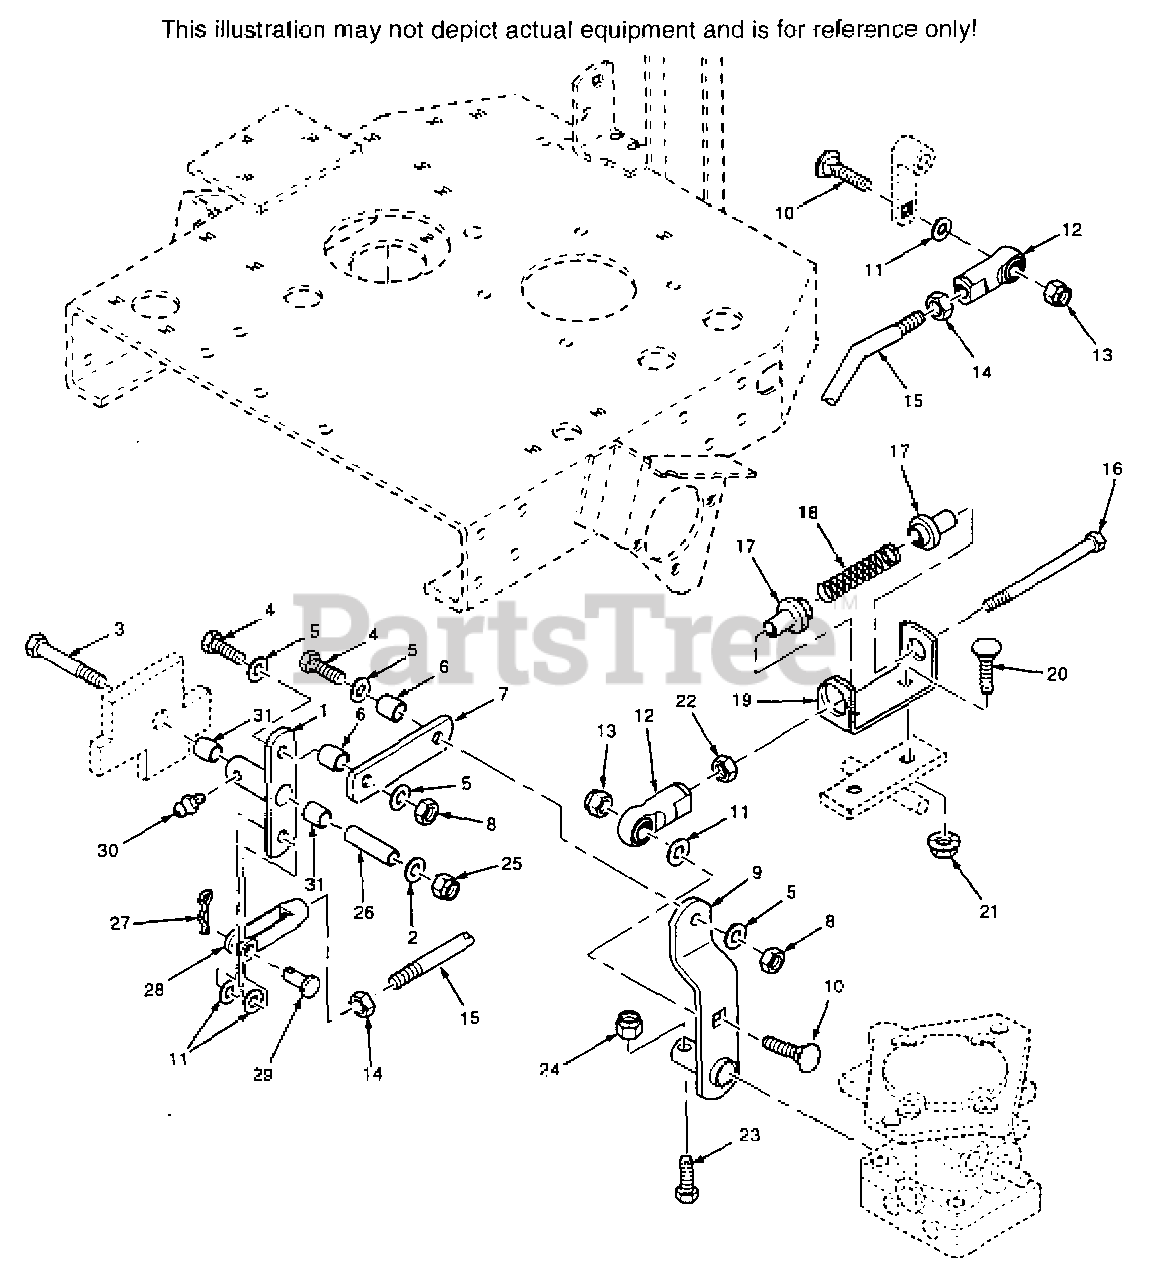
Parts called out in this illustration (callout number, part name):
1	CONTROL LINKAGE, BELLCRANK
6	SLEEVE, PUMP CONTROL LINK
7	LINK, SPEED CONTROL
9	CONTROL ARM, PUMP
11	FLATWASHER, 3/8 X 15/16 X 12 GA.
12	ROD END, RH FEMALE THD 3/8-24
15	CONTROL ROD
16	BOLT, HEX HEAD, 3/8-24 X 6-3/4
17	BUSHING, SPRING KEEPER
18	SPRING, NEUTRAL RETURN
19	RETAINER, NEUTRAL SPRING
21	HEX NUT, SERR. FL. 5/16-18
26	SLEEVE, CONTROL ARM
27	PIN, COTTER
28	CLEVIS, PUMP CONTROL
29	PIN, CLEVIS
30	GREASE FITTING, 1/4-28 SELF TAP
31	BUSHING, BRONZE
